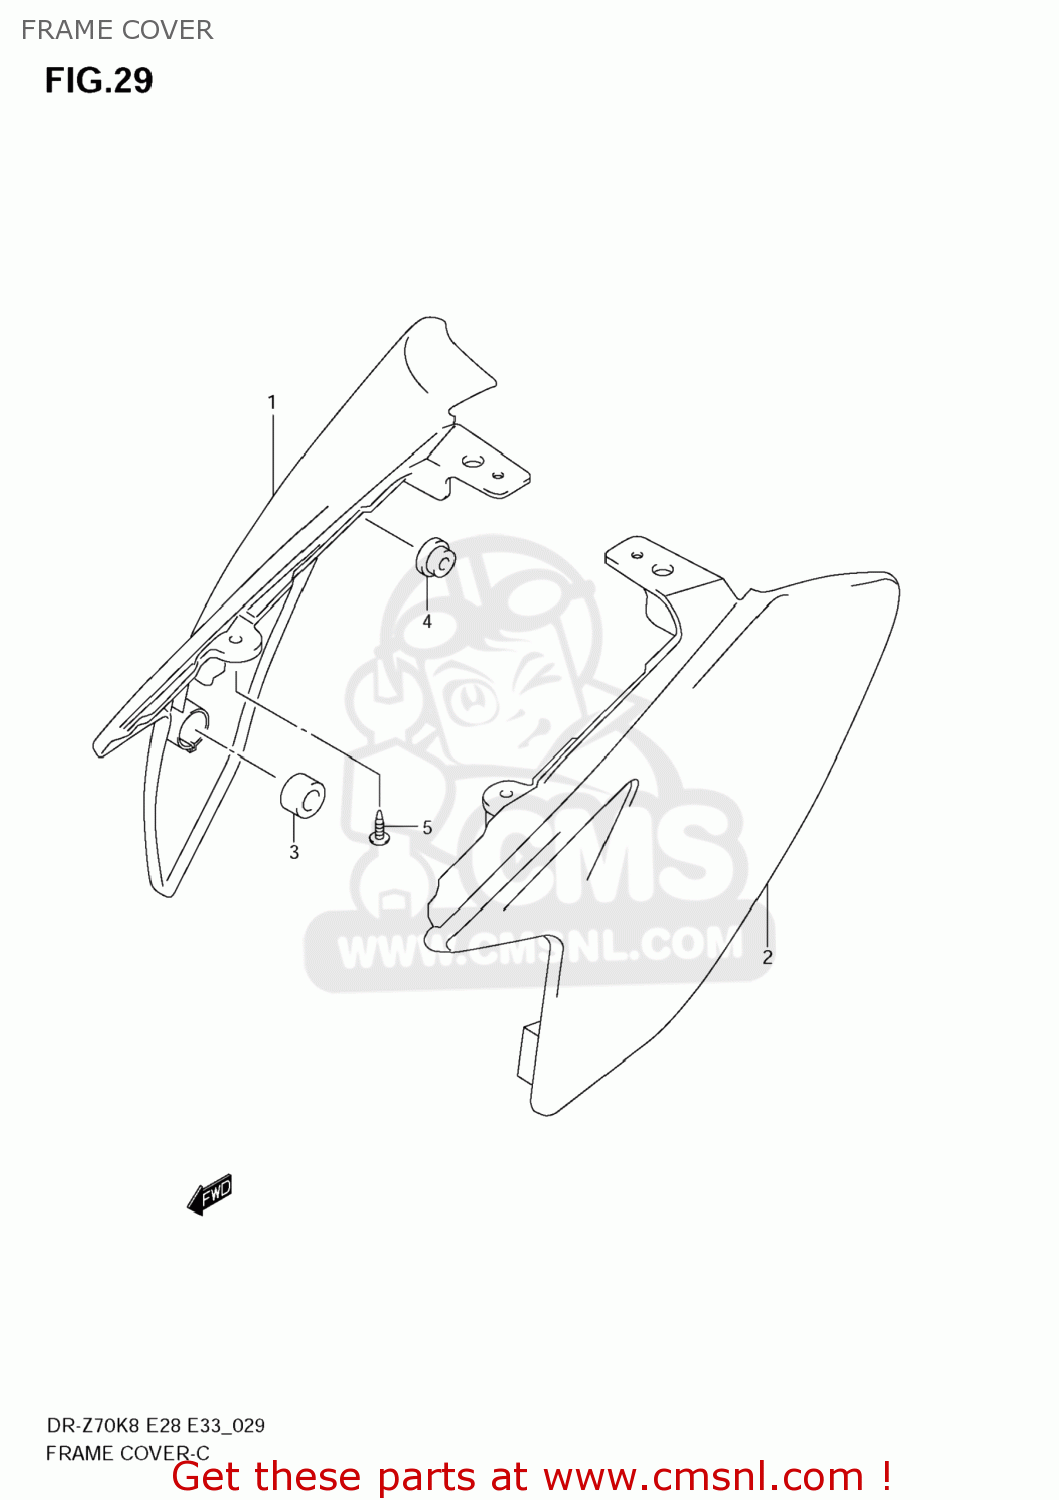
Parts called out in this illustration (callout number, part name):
1	COVER,FRAME,R(WHITE)
2	COVER,FRAME,L(WHITE)
3	CUSHION,FRAME COVER
4	CUSHION
5	SCREW
